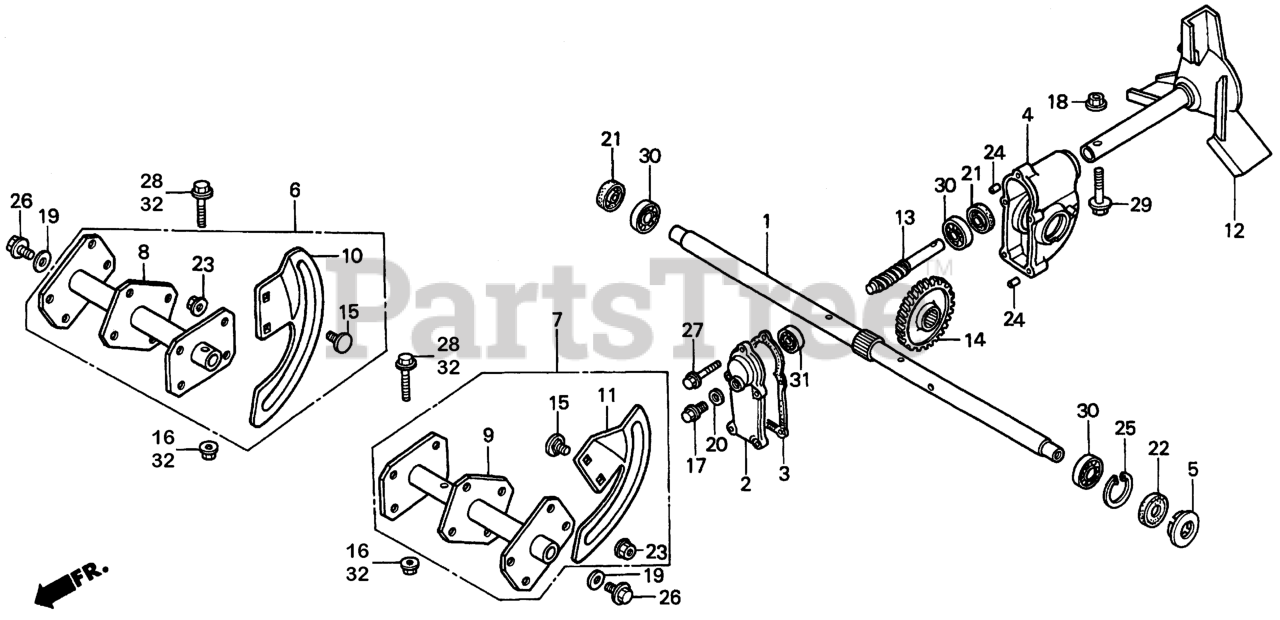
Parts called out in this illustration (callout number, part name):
1	SHAFT, AUGER
2	COVER, AUGER TRANSMISSION
3	GASKET, AUGER TRANSMISSION
4	CASE, AUGER TRANSMISSION
5	CAP, AUGER CASE (NOT AVAILABLE)
6	AUGER ASSY., R. (22")
7	AUGER ASSY., L. (22")
8	FLANGE, R. AUGER (22")
9	FLANGE, L. AUGER (22")
10	STEEL, R. AUGER
11	STEEL, L. AUGER
13	GEAR, DRIVE (5T)
14	GEAR, DRIVEN (55T)
15	BOLT, SPECIAL (9X15)
16	NUT, SELF-LOCK (6MM)
17	BOLT, DRAIN PLUG
18	NUT, FLANGE (8MM)
19	WASHER (8MM)
20	WASHER, DRAIN PLUG (10.2MM)
21	OIL SEAL (20X32X7)
22	OIL SEAL (20X42X8)
23	NUT-WASHER (8MM)
24	PIN A, DOWEL (8X14)
25	CIRCLIP (INNER) (42MM)
26	BOLT, FLANGE (8X16) Use from Engine SN 1000016.
27	BOLT, FLANGE (6X32)
28	BOLT, FLANGE (6X35)
29	BOLT, FLANGE (8X35)
30	BEARING, RADIAL BALL (6004)
31	BEARING, RADIAL BALL (6202)
